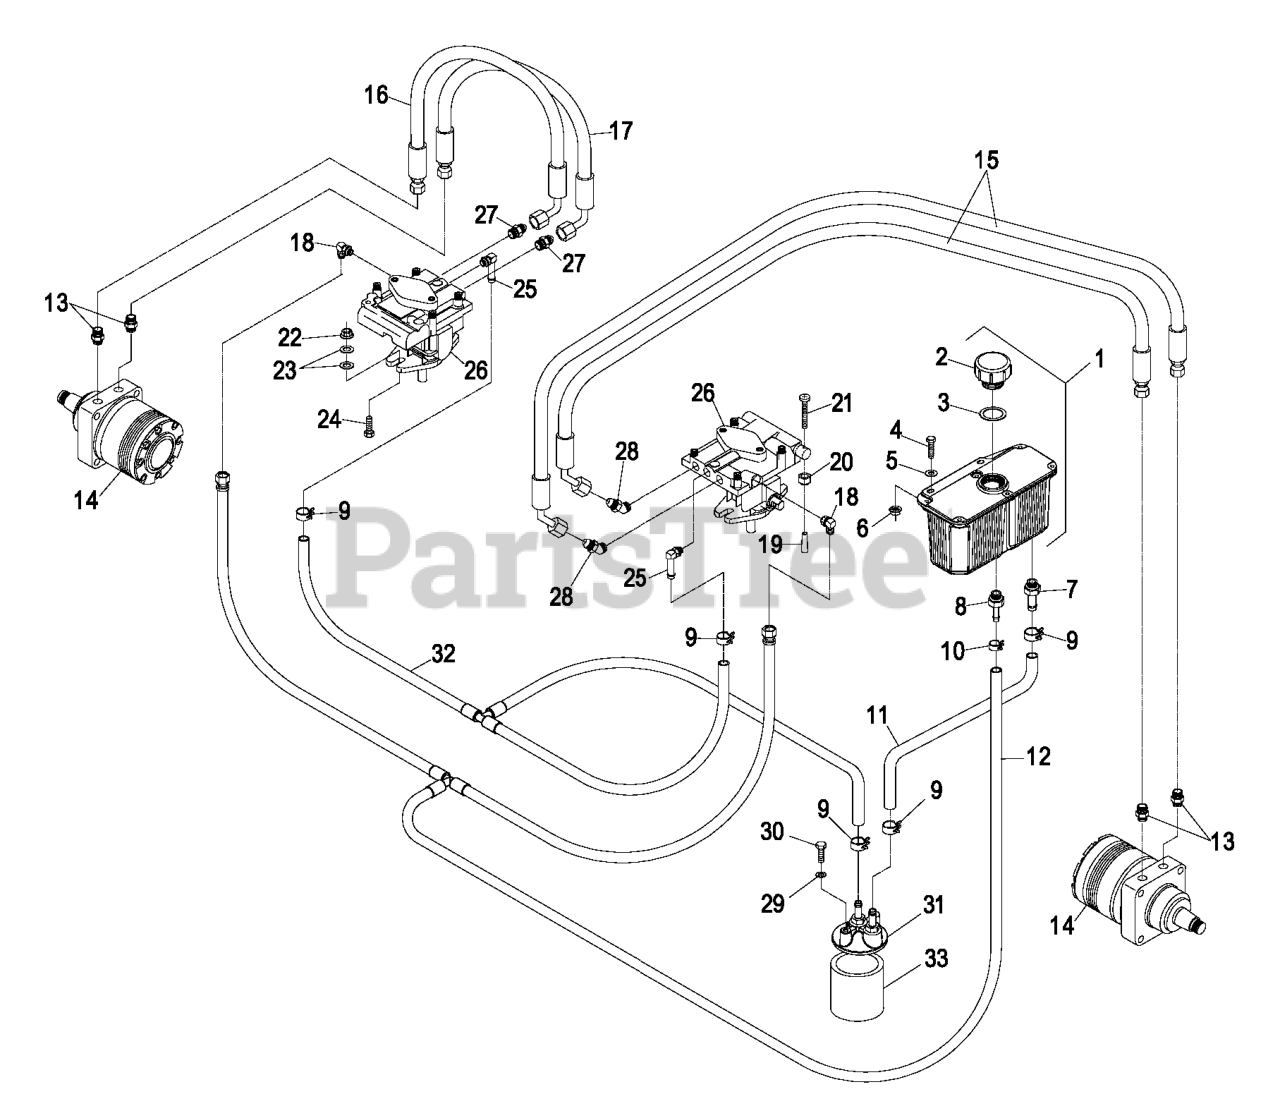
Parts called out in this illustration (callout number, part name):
1	HYD RESERVOIR ASM
2	Cap-Reservoir, HYD
3	GASKET-CAP
4	SCREW-HH
5	WASHER-FLAT
7	ADAPTER-STRAIGHT
8	ADAPTER-STRAIGHT
9	CLAMP-HOSE
10	CLAMP-HOSE
13	FITTING-STRAIGHT
14	HYD MOTOR ASM
15	HOSE,HIGH PRESSURE
17	HOSE-PRESSURE, HIGH
18	FITTING-90 DEG
19	GRIP-VALVE, DUMP
20	NUT-LOCK, NI
22	NUT-HHF, WHIZ
23	WASHER-FLAT
24	SCREW-HH
25	FITTING
27	FITTING-STRAIGHT
28	FITTING-HYD, 45 DEG
29	WASHER-LOCK
30	SCREW-HH
31	FILTER HEAD ASM
